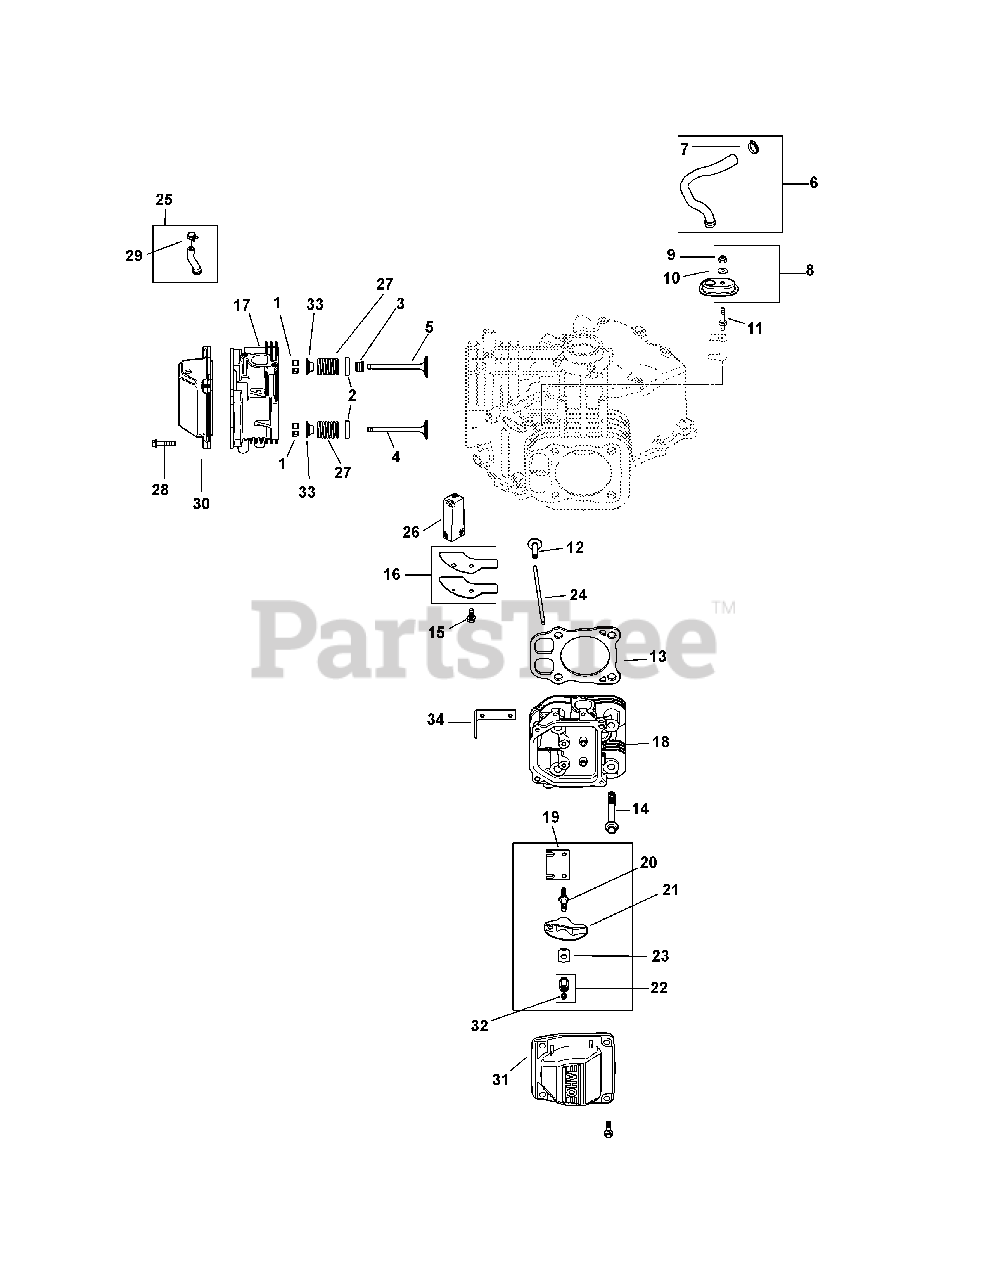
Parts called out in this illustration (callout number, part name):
1	Retainer Kit
2	Spring Retainer
3	Valve Stem Seal
4	Exhaust Valve (STD)
5	Intake Valve (STD)
6	Breather Hose Kit (Inc. #7)
7	Hose Clamp, 1/2
8	Housing Breather Kit (Inc. #9 & 10)
9	Lock Nut, M5 x 8
10	Sealing Washer
11	Breather Cover Stud
13	Cylinder Head Gasket Kit
14	Flange Screw, M10 x 1.5 x 90
15	Flange Screw, M6 x 1.0 x 16
16	Breather Cover
17	Cylinder Head Assembly Kit, #1
18	Cylinder Head Assembly Kit, #2
22	Hex Nut Assembly (Inc. #32)
23	Rocker Arm Pivot
25	Fuel Pump Hose Kit (Inc. #29)
26	Breather Filter
27	Valve Spring
28	Pan Head Screw
30	Rocker Cover
33	Valve Spring Cap
34	Lifting Strap
